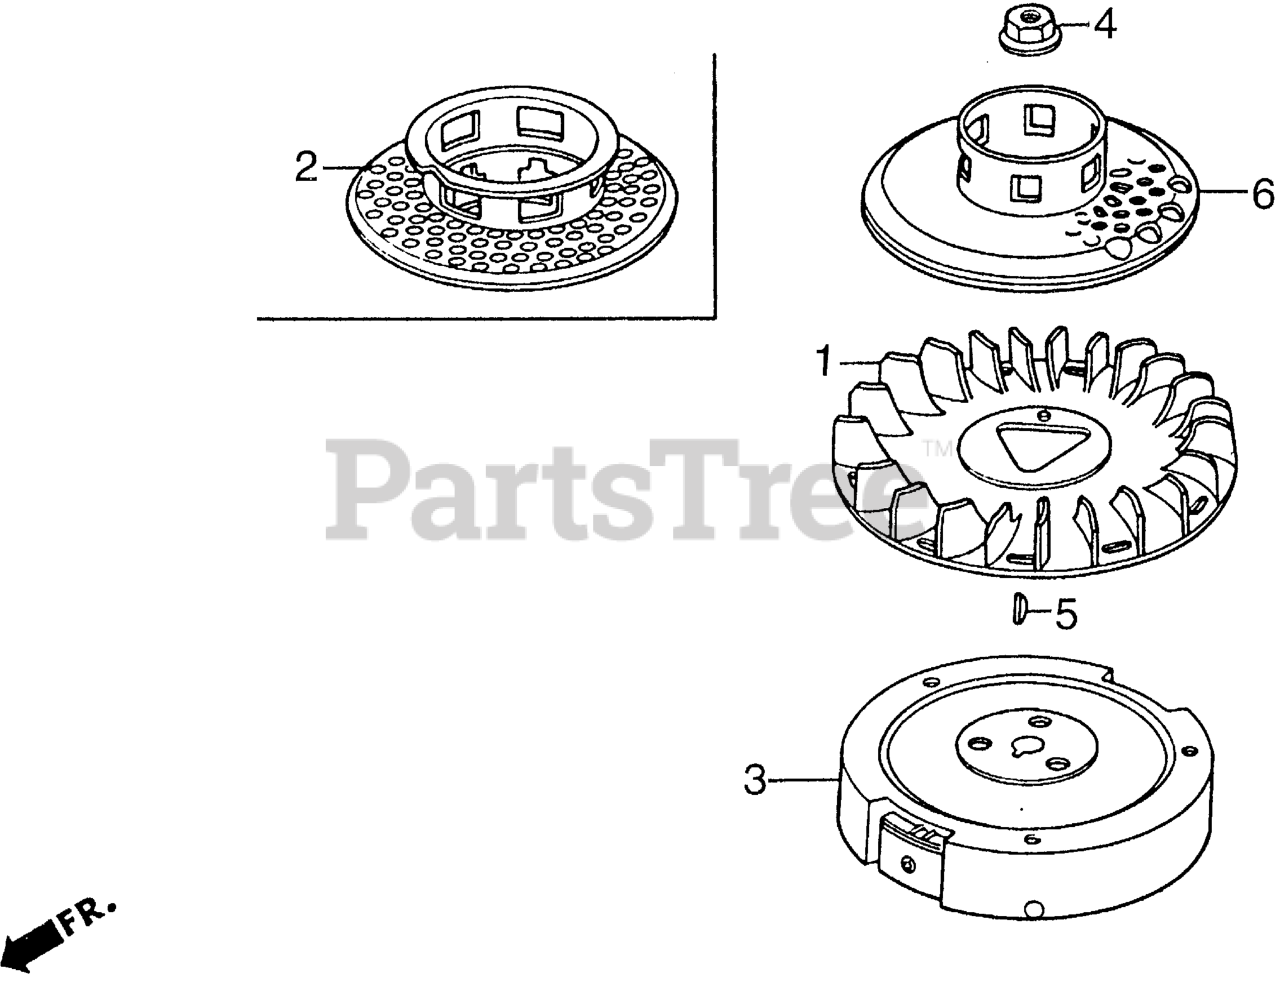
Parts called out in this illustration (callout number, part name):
1	FAN, COOLING
2	PULLEY, STARTER Use up to Engine SN 2013098.
3	FLYWHEEL
4	NUT, SPECIAL (16MM)
5	KEY, SPECIAL WOODRUFF (25X18)
6	PULLEY, STARTER (SCREEN GRID)
